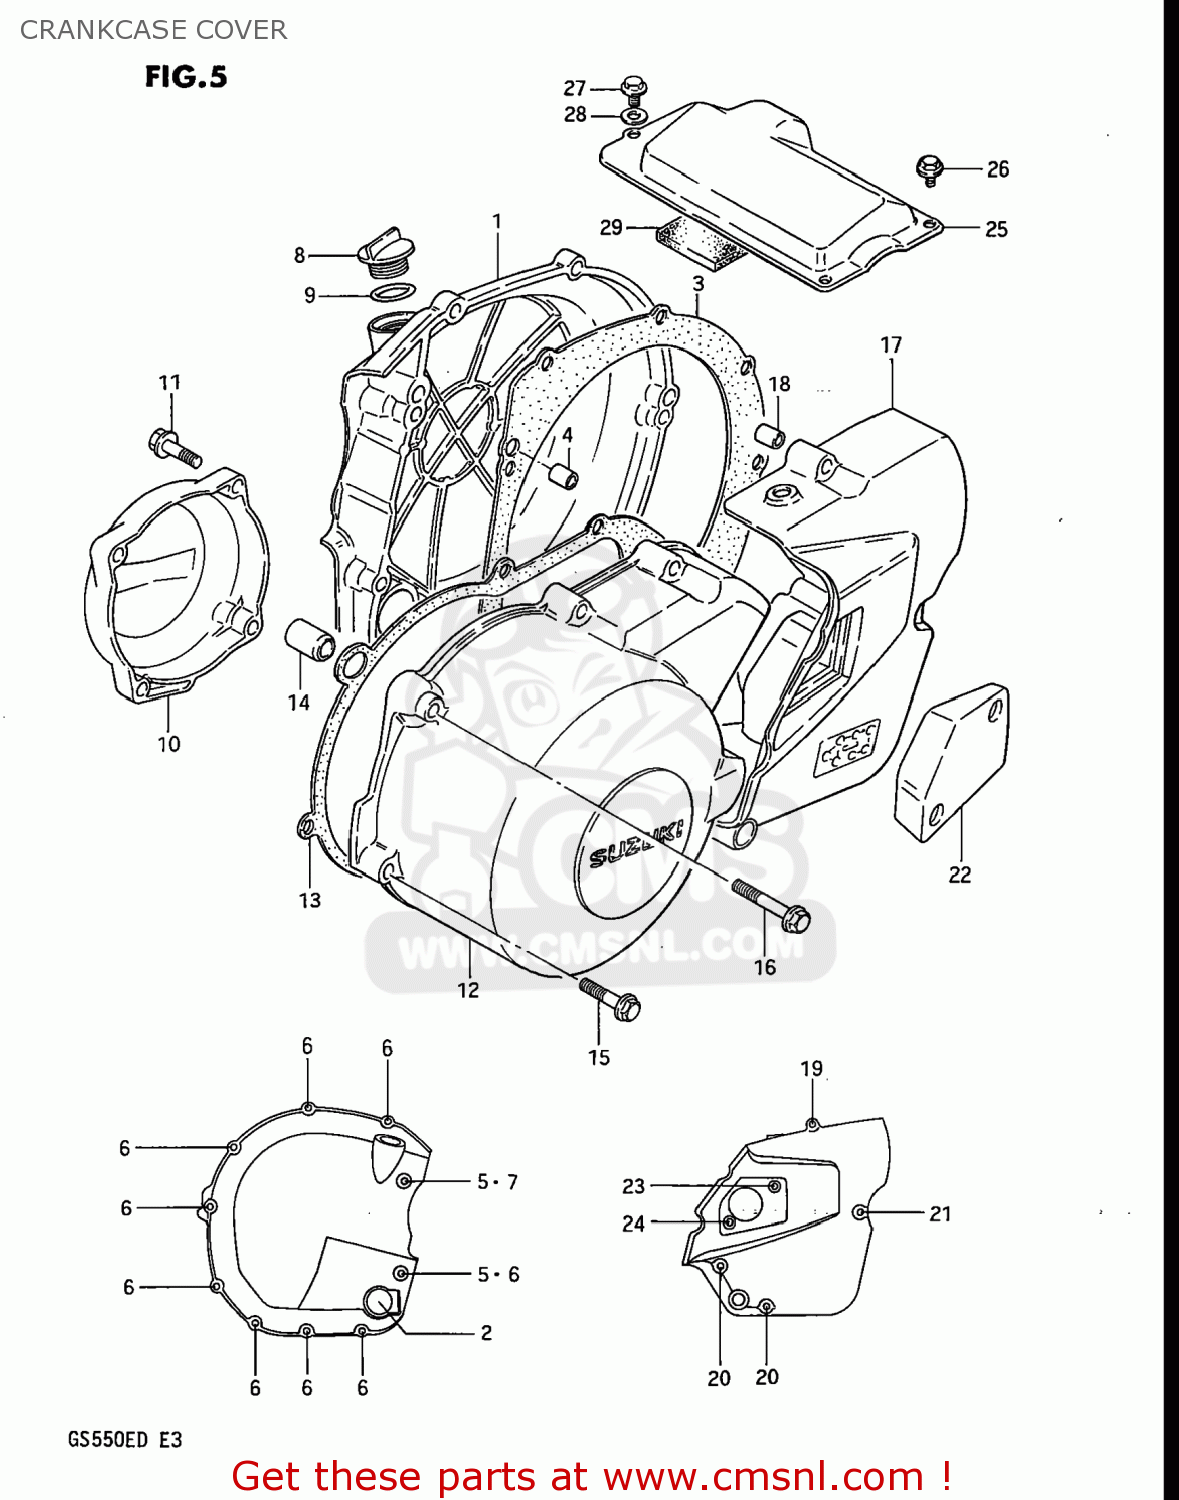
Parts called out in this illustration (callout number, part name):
1	COVER,CLUTCH
2	LENS,OIL LEVEL CHECK
3	GASKET,CLUTCH COVER (MCA)
4	PIN
5	WASHER
6	BOLT 6X25
7	BOLT 6X35
8	PLUG
9	O RING(D:3.1,ID:16.8)
10	COVER,CONTACT BREAKER
11	BOLT 6X25
12	COVER,MAGNETO
13	GASKET,MAGNETO COVER (MCA)
14	PIN (11X20)(SUS)
15	BOLT 6X30
16	BOLT
17	COVER,ENGINE SPROCKET
18	PIN
19	BOLT 6X40
20	BOLT (6X55)
21	BOLT 6X80
22	CAP,CLUTCH RELEASE ADJUST
23	SCREW
24	SCREW
25	COVER,STARTER MOTOR
26	BOLT
27	BOLT
28	WASHER
29	DAMPER,STARTER MOTOR CLUTCH
